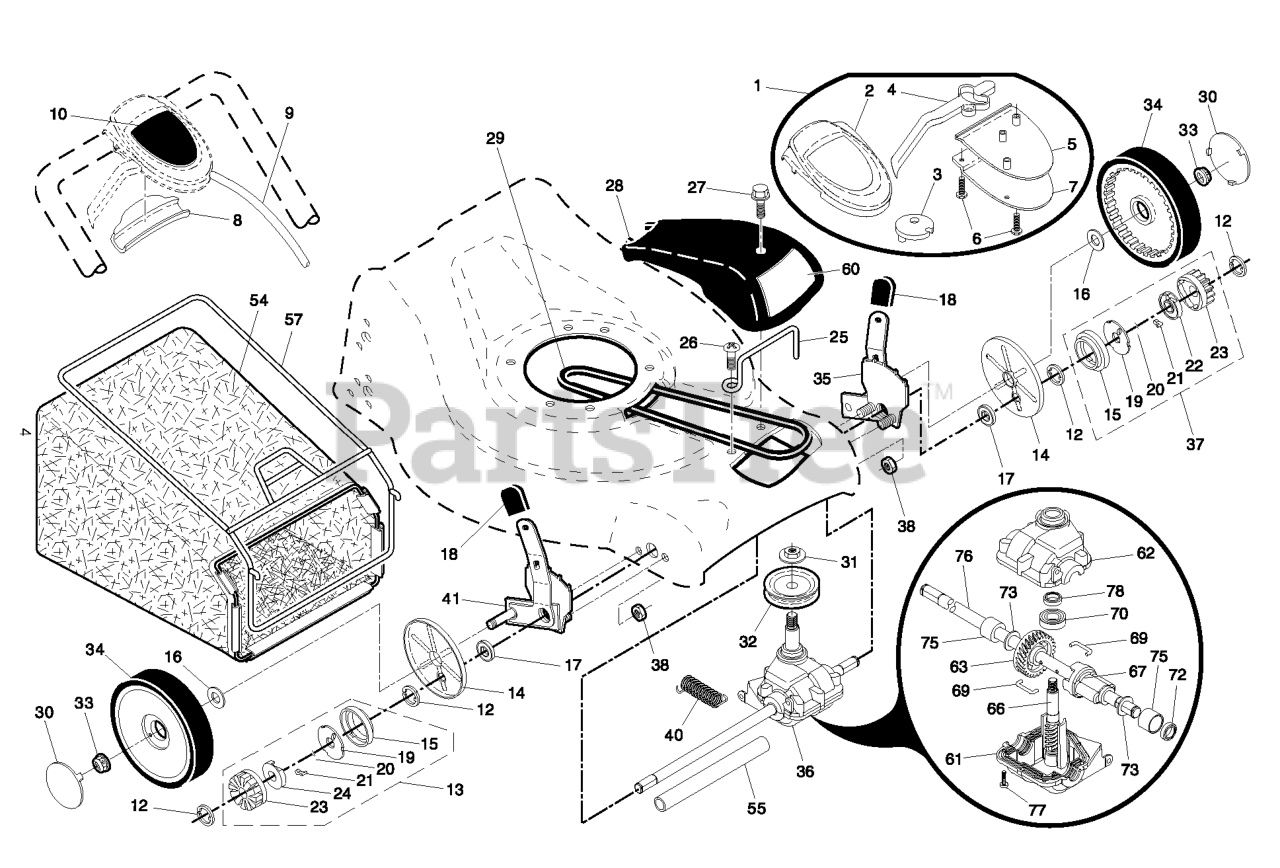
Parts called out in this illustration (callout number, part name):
2	CASE.TOP.GRAY
3	PULLEY.CAM.DRIVE.CONTROL.HV
4	LEVER
5	CASE BOTTOM
6	SCREW, PHILLIPS HEAD 10 X 5/8
7	BRACKET, DRIVE CONTROL
8	CAP.DRIVE.CONTROL.BLACK.HI-VAC
9	CABLE.ASM.
10	DECAL, DRIVE
12	E-RING 7/16 RE
13	PINION ASSY, RH
14	COVER.DUST.WHEEL
15	SEAL.PINION
16	WASHER FLUT
17	BEARING, BALL
18	SELECTOR KNOB
19	DISC.DRIVE.21.EZ-WALK
20	SPRING, TORSION
21	PAWL.DRIVE.21.EZ-WALK
22	RETAINER.DRIVE.21.EZ-WALK.LT
23	GEAR, PINION
24	RETAINER, DRIVE, RH
25	KEEPER, BELT
26	BOLT.HEX.HDWSH.5/16-18X1.00
27	SCREW, HEX HD TAPPING #10-24 1
28	COVER.DRIVE.21.FWGD.GRAY
30	HUBCAP
31	FLANGED LOCKNUT 3/8-16 ZINC
32	PULLEY
35	KIT.ADJUSTER.ASM.EZ.LH
36	TRANSMISSION.21RD.FGDE
37	PINION ASSY, LH
38	LOCKNUT.NYLOC.1/4-20
40	SPRING, RETURN
41	KIT.ADJUSTER.ASM.EZ(169770).RT
55	DRIVESHAFT COVER
57	BAG FRAME
60	DECAL DRIVE COVER
61	LOWER CASE
62	UPPER CASE
63	GEAR.27.TEETH.WALK.MOWER
66	SHAFT INPUT (13056)
69	WIRE, FORMED (15966)
72	SEAL.OUTPUT.SHAFT
76	SHAFT OUTPUT (12198)
78	SEAL INPUT SHAFT
